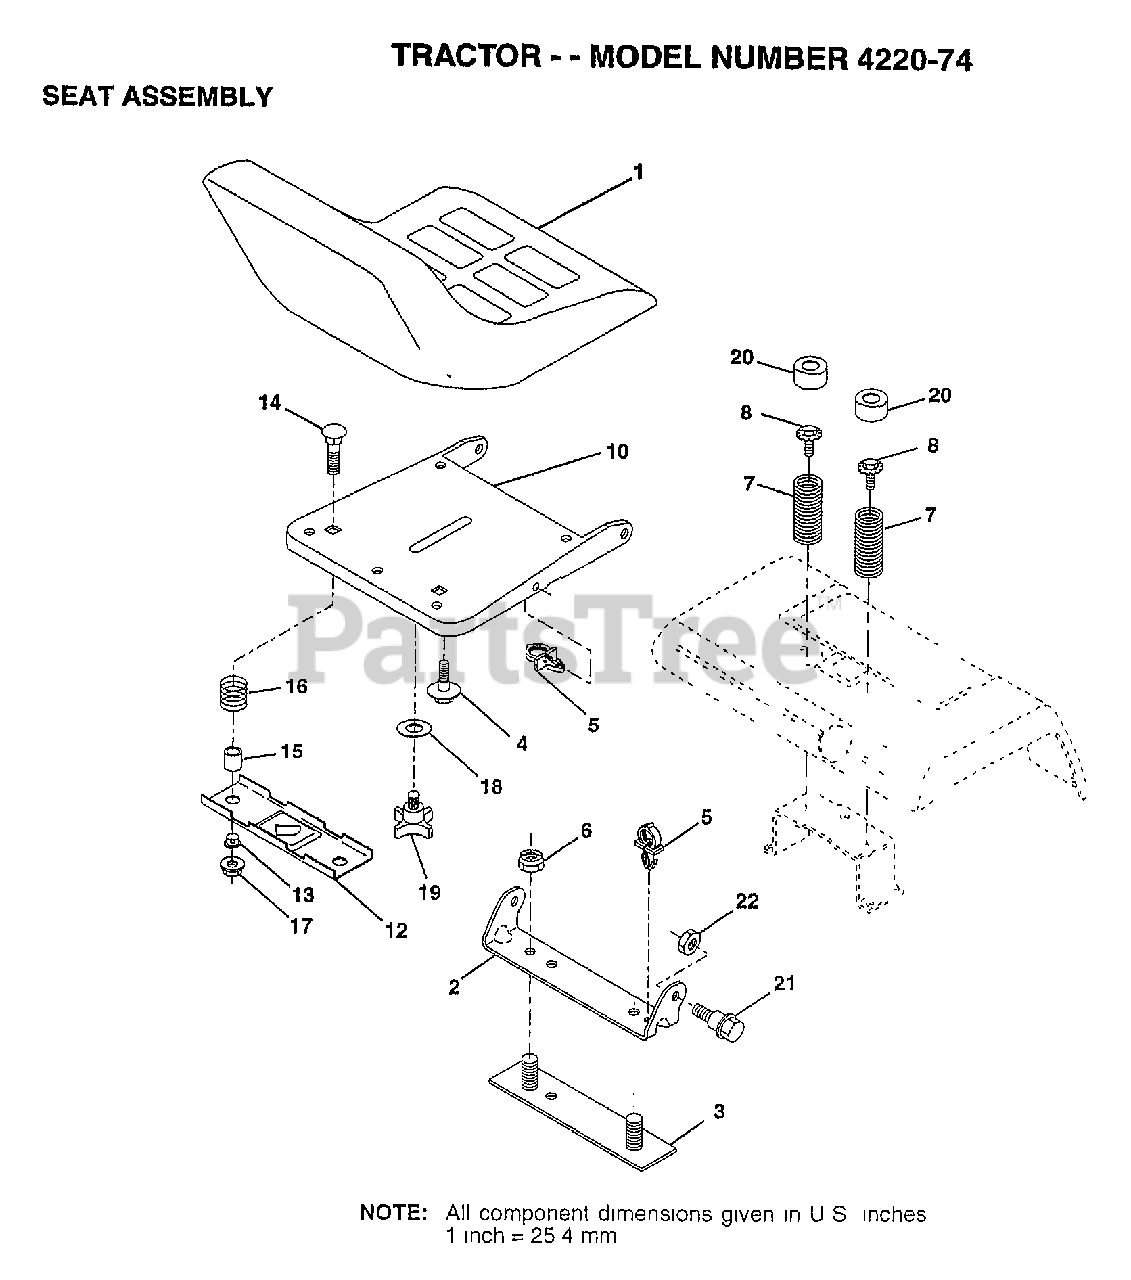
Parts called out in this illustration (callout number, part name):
2	BRACKET PVT SEAT
3	STRAP ASM FENDER
4	"BOLT,SHOULDER"
5	CLIP.PUSH-IN.HING
6	NUT
7	SPRING COMPRESSIO
8	BOLT.5/16-18.UNC
10	PAN-SEAT
12	BRKT SWITCH
13	BUSHING
15	SPACER SPLIT
16	SPRING COMPRESSED
18	WASHER
19	"KNOB 1/2"" YT"
20	CAP SPRING
21	"BOLT,SHOULDER"
